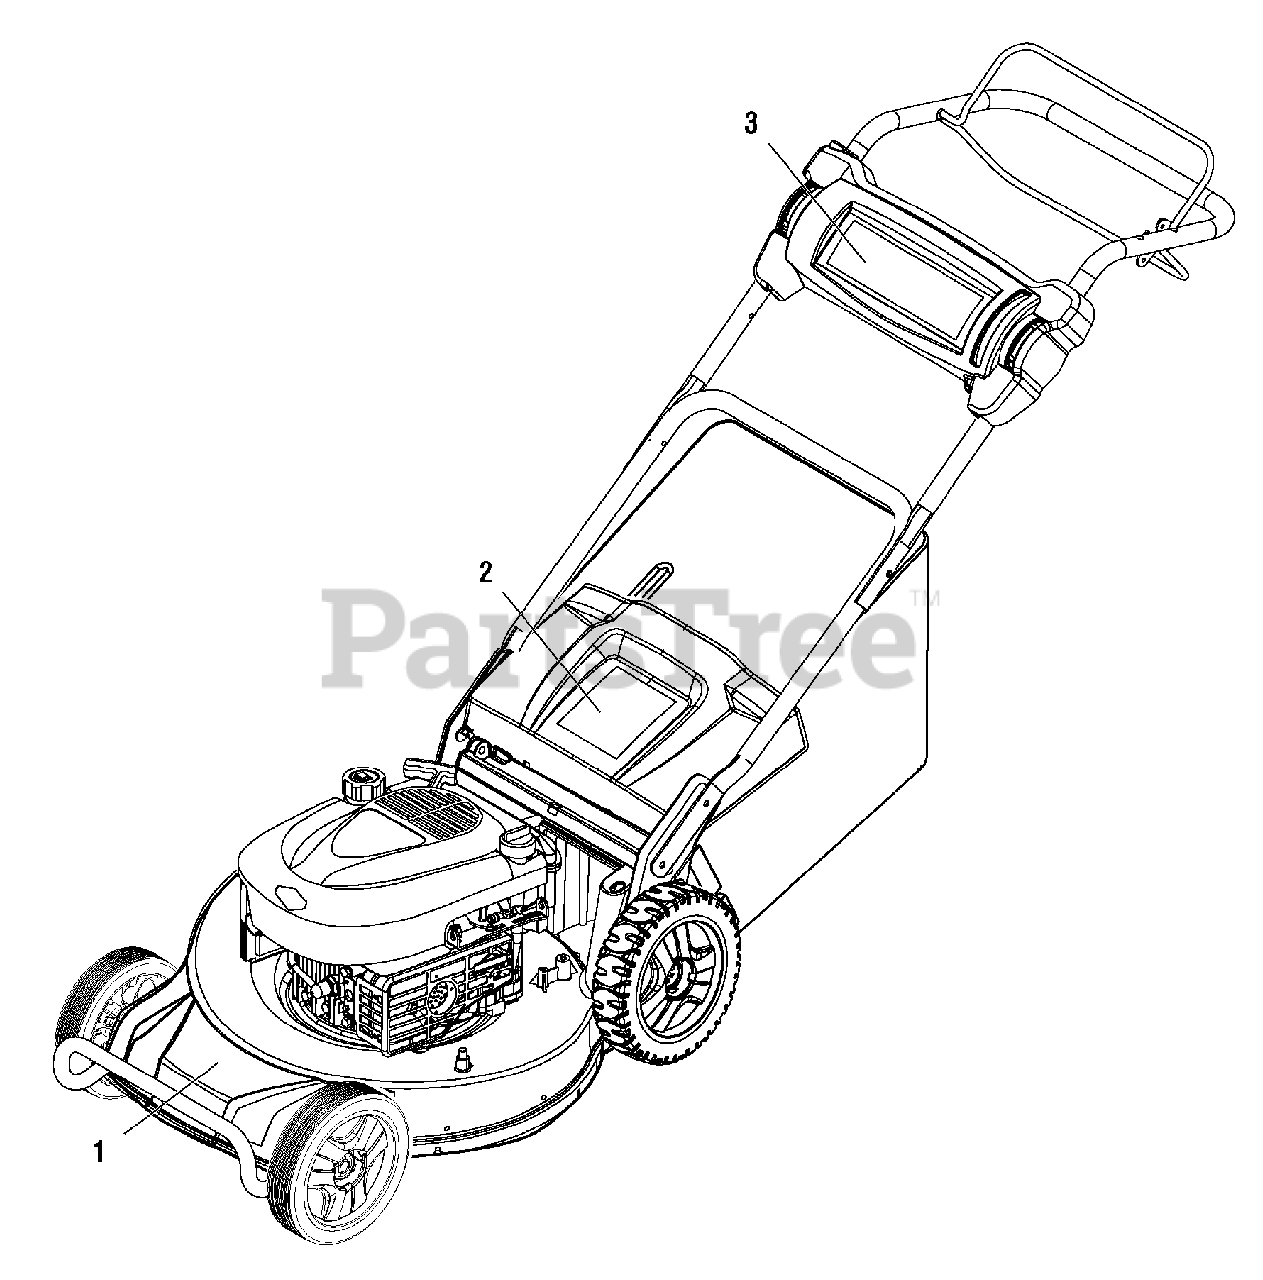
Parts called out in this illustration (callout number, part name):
1	DECAL, Logo, Deck
2	DECAL, Safety
3	DECAL, Logo, Cover
